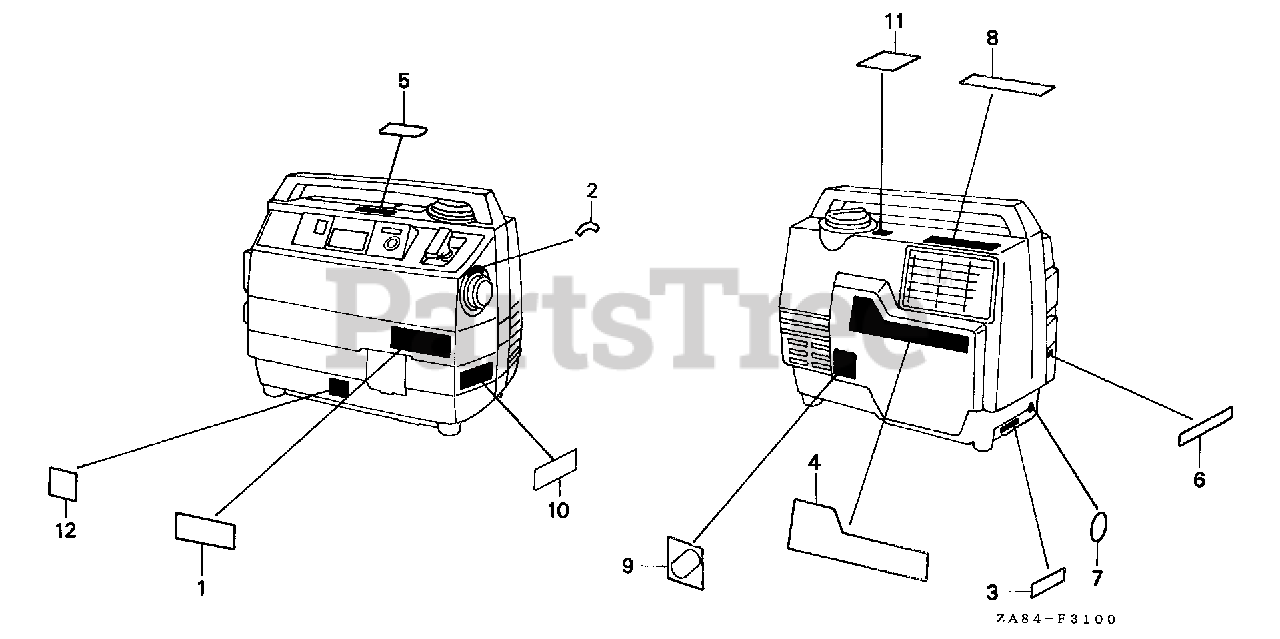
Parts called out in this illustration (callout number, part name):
1	MARK, EMBLEM (BLACK)
2	MARK, ENGINE SWITCH
3	MARK, TOOL
4	MARK, CAUTION
5	LABEL, RAIN WARNING (ENGLISH)
6	MARK, D.C. CAUTION *NH121* (PEARL SHELL WHITE)
7	MARK, GROUND
8	MARK, EX. CAUTION
9	MARK, FREQUENCY POSITION
10	LABEL, CONNECT WARNING (ENGLISH)
11	MARK, FUEL
12	MARK, OIL CAUTION
